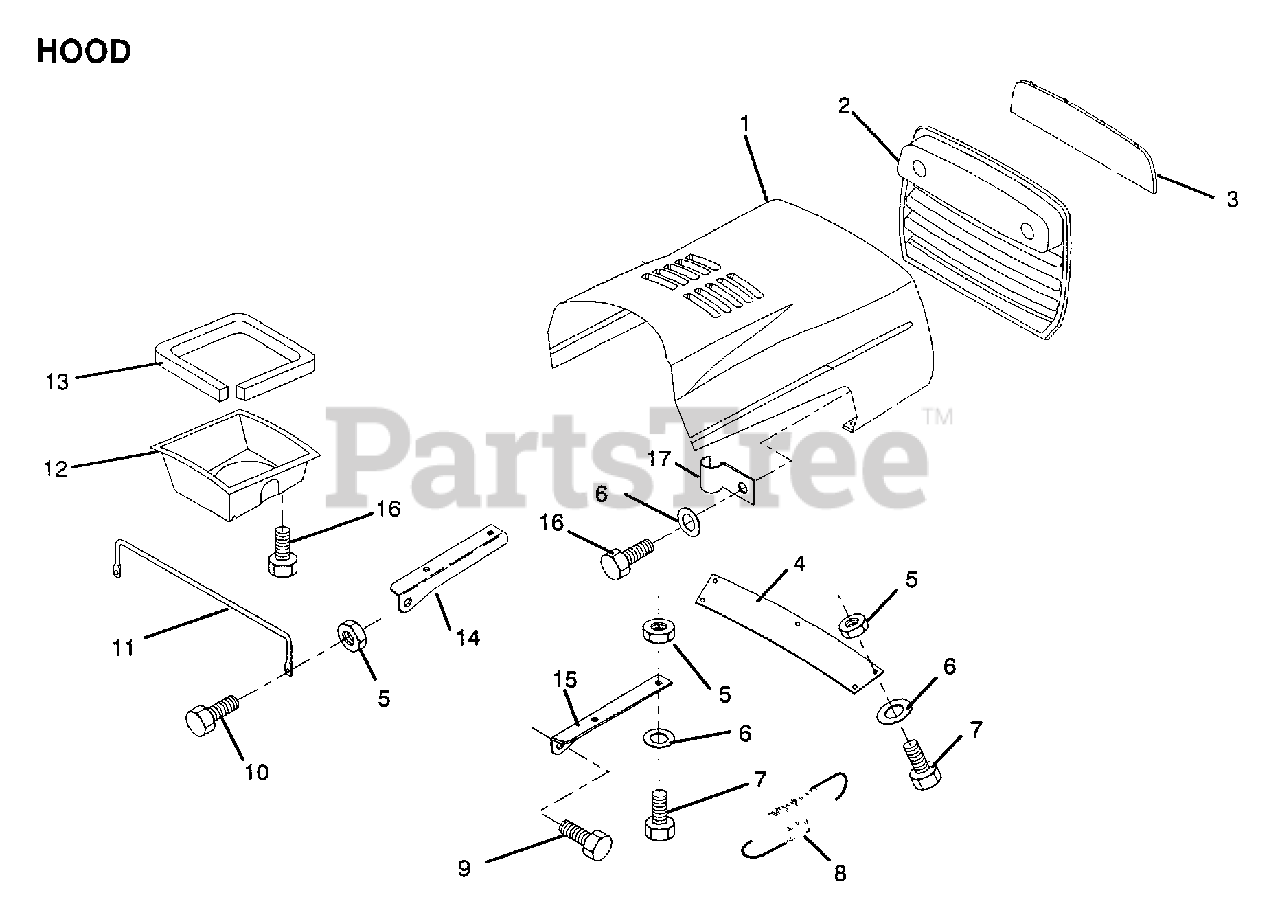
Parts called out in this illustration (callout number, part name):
2	GRILL
3	LENS
4	"STRAP,GRILL T"
5	NUT
6	WASHER
7	BOLT
8	EXT SPRING
11	"BRACE,HOOD"
12	"DUCT,AIR"
13	FOAM STRIP LT
14	BRKT HOOD LH
15	BRKT HOOD RH
17	CLIP T
